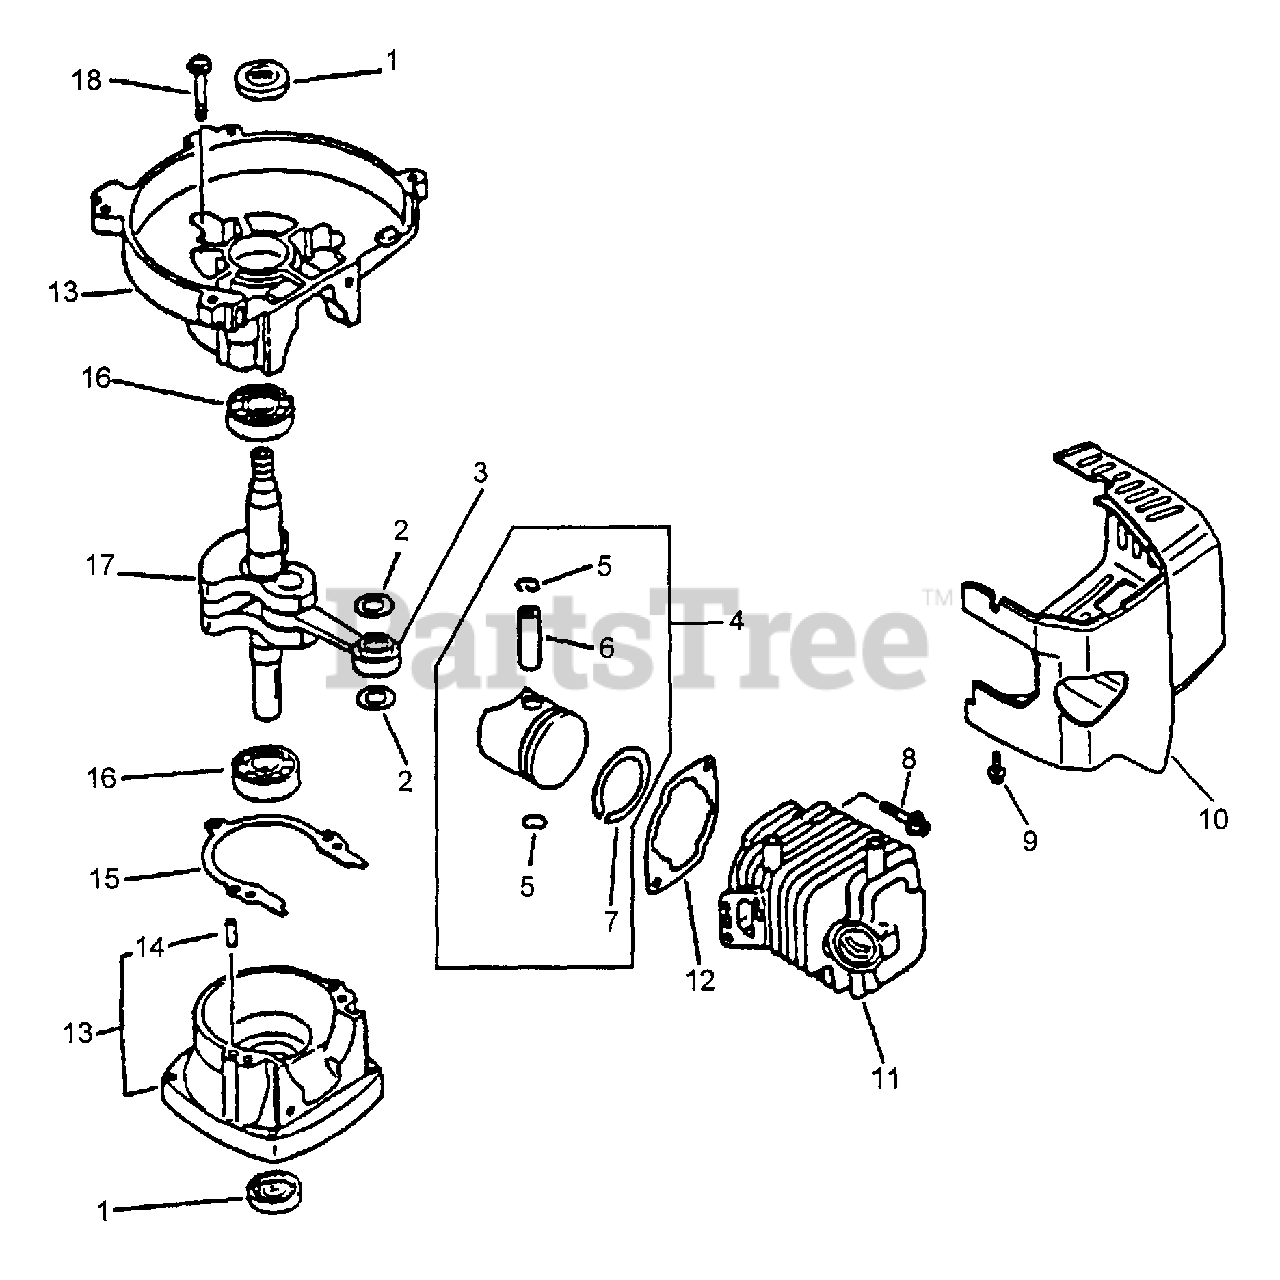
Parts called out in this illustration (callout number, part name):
1	SEAL, OIL 12
2	WASHER, THRUST
3	BEARING, NEEDLE
4	PISTON KIT
5	RING, SNAP
6	PIN, PISTON 8
7	RING, PISTON
8	BOLT 5×22
9	BOLT 4×20
10	ENGINE COVER KIT - GRAY
10	COVER, ENGINE
11	CYLINDER
12	GASKET, CYLINDER
13	CRANKCASE KIT
14	PIN, LOCATING 4
15	GASKET, CRANKCASE
16	BEARING, BALL - 6201 C3
17	CRANKSHAFT ASSY
17	CRANKSHAFT
18	BOLT 5×28
